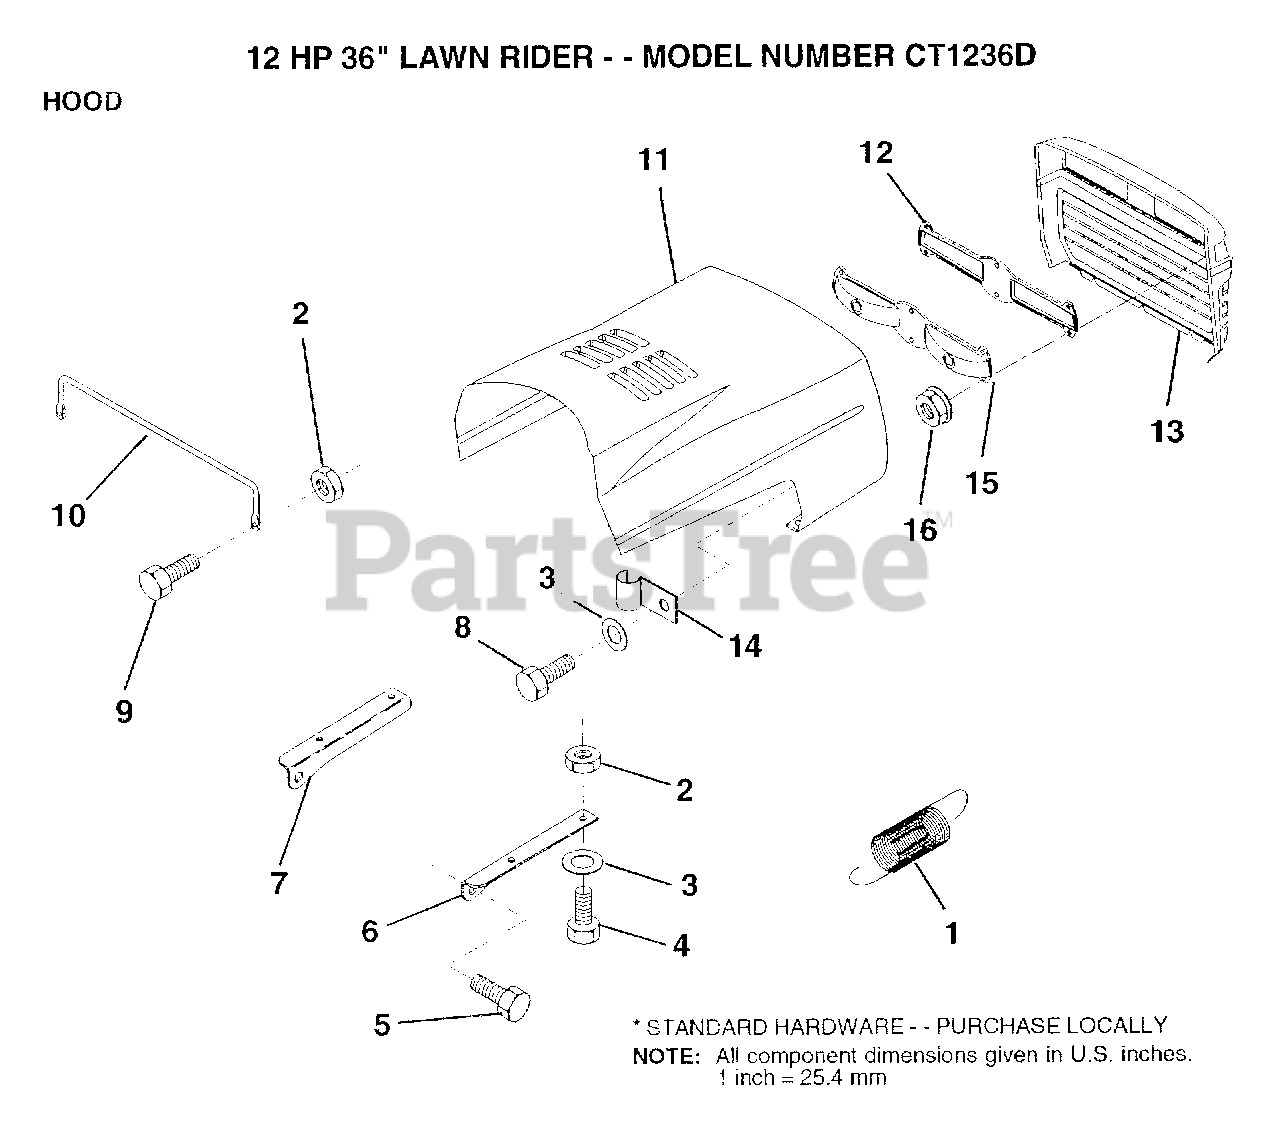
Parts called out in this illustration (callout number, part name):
1	EXT SPRING
2	NUT
3	WASHER
4	BOLT
6	BRKT HOOD RH
7	BRKT HOOD LH
10	"BRACE,HOOD"
14	CLIP T
16	NUT
